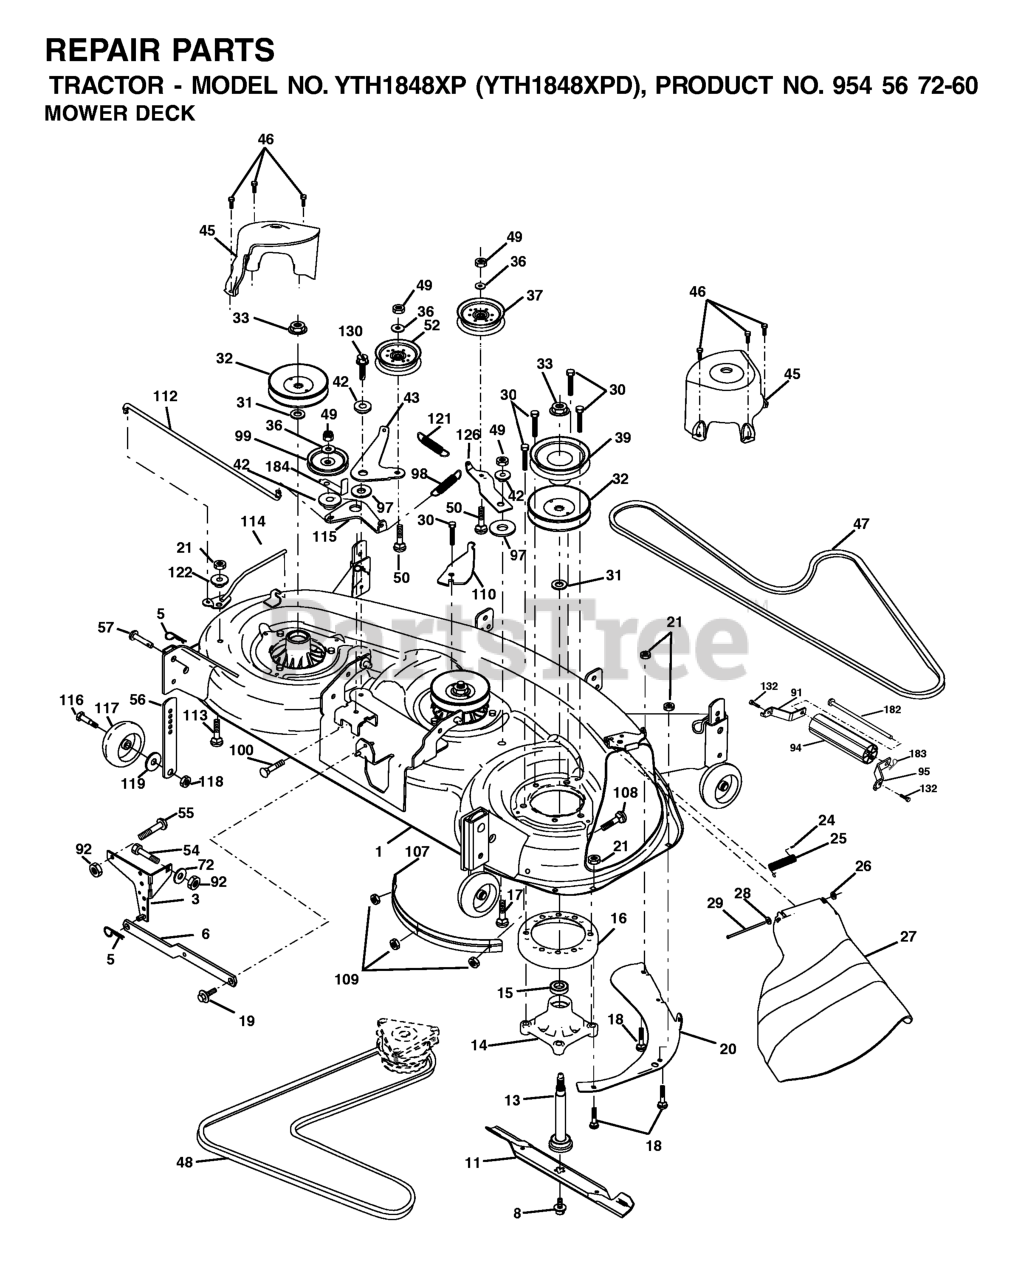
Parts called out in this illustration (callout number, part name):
1	DECK WELDMENT
3	BRKT ASM SWAY BAR
5	RETAINER-SPRNG RB
6	BAR SWAY DECK
8	BOLT 7/16 ASM BLADE
11	48" HI-LIFT BLADE
13	SHAFT ASM W/LOWER BEARING
14	HOUSING, MANDREL 48"
16	STRIPPER.MANDREL.ROUND.BLACK
17	BOLT
18	BOLT
19	BOLT SHD 5/16-18
20	BAFFLE, VORTEX MWR
21	LOCKNUT
24	CAP-SLEEVE LT
25	SPRING, TORSION
26	NUT PUSH M
27	DEFLECTOR SUBS TO 532 180655
28	Washer 11/32 x 5/8 x 16 Ga SD
29	ROD.HINGE
30	SCREW, WASHER HEAD
31	WASHER
32	PULLEY, MANDREL
33	NUT, FLG TOPLOCK 9/16"
36	WASHER
37	PULLEY.IDLER.FLAT
39	PULLEY.DRIVEN.DECK.48'
42	SPACER RETAINER
43	ARM, IDLER SECONDARY
45	COVER, MANDREL DECK
46	SCREW.1/4-20X5/8
47	V-BELT, MWR SECONDARY
48	V-BELT PRIMARY 48"
50	BOLT.3/8-16X1.50
52	PULLEY.IDLER.FLAT.46.PR.DR.
55	BOLT D
56	BAR.ADJUST.WHEEL.ANTI.SCALP.BL
57	RIVET.PIN.HEAD.YELLOW.
72	WASHER
91	BRKT.NOSEROLLER.LH.48"
92	NUT
94	NOSE ROLLER 48"
95	BRKT.NOSEROLLER.RH.48"
97	HARDENED WASHER
98	SPRING PRIMARY DRIVE
99	PULLEY,IDLER"V"
107	BAFFLE.VAC.EDGE.MOWER.48"
109	NUT.CROWNLOCK.1/4
110	ARM, SPRING SECONDARY
112	LEVER, TENSION RELIEF LINK
114	LEVER ASM, TENSION RELIEF
115	ARM, SPRING TENSION RELIEF
116	BOLT, SHOULDER
117	WHEEL GAGE DONUT
118	LOCKNUT
119	WASHER.5/16.FLAT.STE.STD.
121	SPRING.DRIVE.SECONDARY.48".DEC
122	BUSHING, PIVOT TENSION RELIEF
126	ARM, IDLER PRIMARY DECK
130	SCREW 3/8-16X1
132	SCREW 3/8-16X3/4
182	ROD.ROLLER.NOSE.NARROW.48"
183	SPRING RETAINER
184	KEEPER BELT IDLER PLATED
